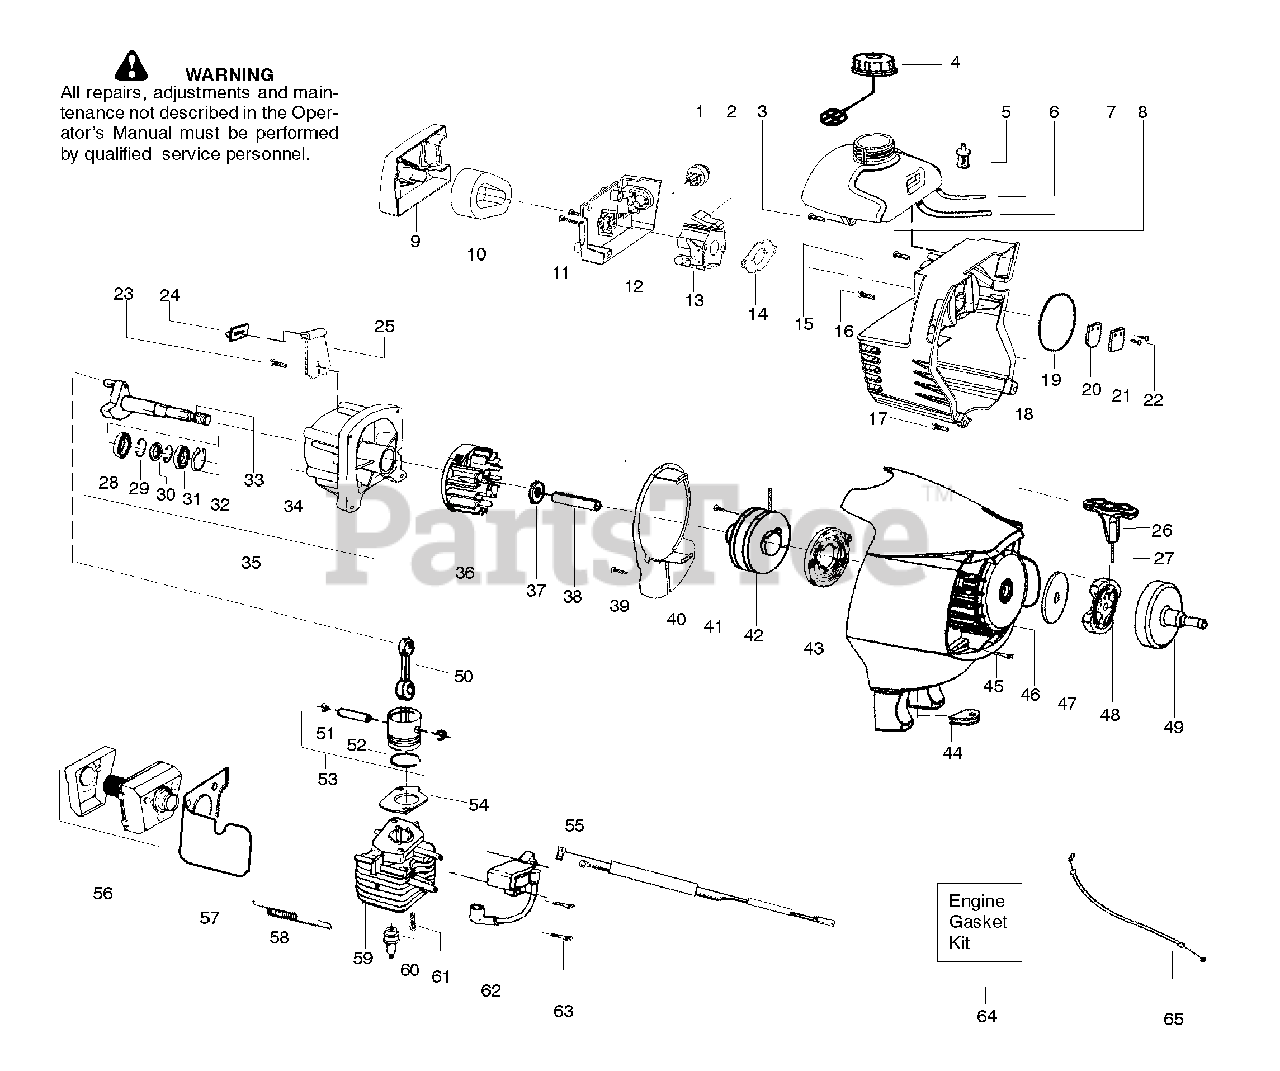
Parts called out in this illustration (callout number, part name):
1	Bulb-Purge
2	Kit-Choke Lever
3	Screw-tank
4	Cap-Fuel w/ret.
5	Assy-Fuel pickup
6	Kit-Carb./Purge Fuel line
7	Kit-Tank/Purge Fuel line
9	Cover-Air box
10	Filter-Air
11	Screw-Carb.
13	Assy-Carb
14	Gasket-Carb.
15	Assy-Fuel Tank
16	Screw-Crankcase
17	Screw-Shroud
19	O-ring-Shroud
20	Valve-Reed
21	Stop-Reed
22	Screw-Reed stop
23	Screw-Retainer
24	Isolator-Tank
25	Ret.-Tank
26	Handle-Starter
27	Kit-Rope
28	Bearing-Inner
29	Retainer
31	Bearing-Outer
32	Ret.-Crankshaft
33	Assy-Crankshaft
34	Assy-Crankcase
35	Assy-C'case/C'shaft
36	Assy-Flywheel
39	Screw-Baffle
40	Plate-Baffle
41	Screw-Rope
42	Kit-Pulley
43	Spring-Starter
45	Screw-F/hsg.
46	Assy.-Fan Housing
47	Washer-Clutch
48	Assy-Clutch
49	Assy-Clutch Drum
50	Assy-Conn. Rod
51	Ret.-Piston pin
52	Ring-Piston
53	Kit-Piston
54	Gasket-Cylinder
55	Assy-Leadwire
56	Kit-Muffler
58	Spring-Muffler
59	Cylinder
60	Plug-Spark
61	Bolt-Cyl. 1/4-20'
62	Module-Ignition
63	Screw-Module
64	Kit-Gasket
65	Assy-Throttle cable
